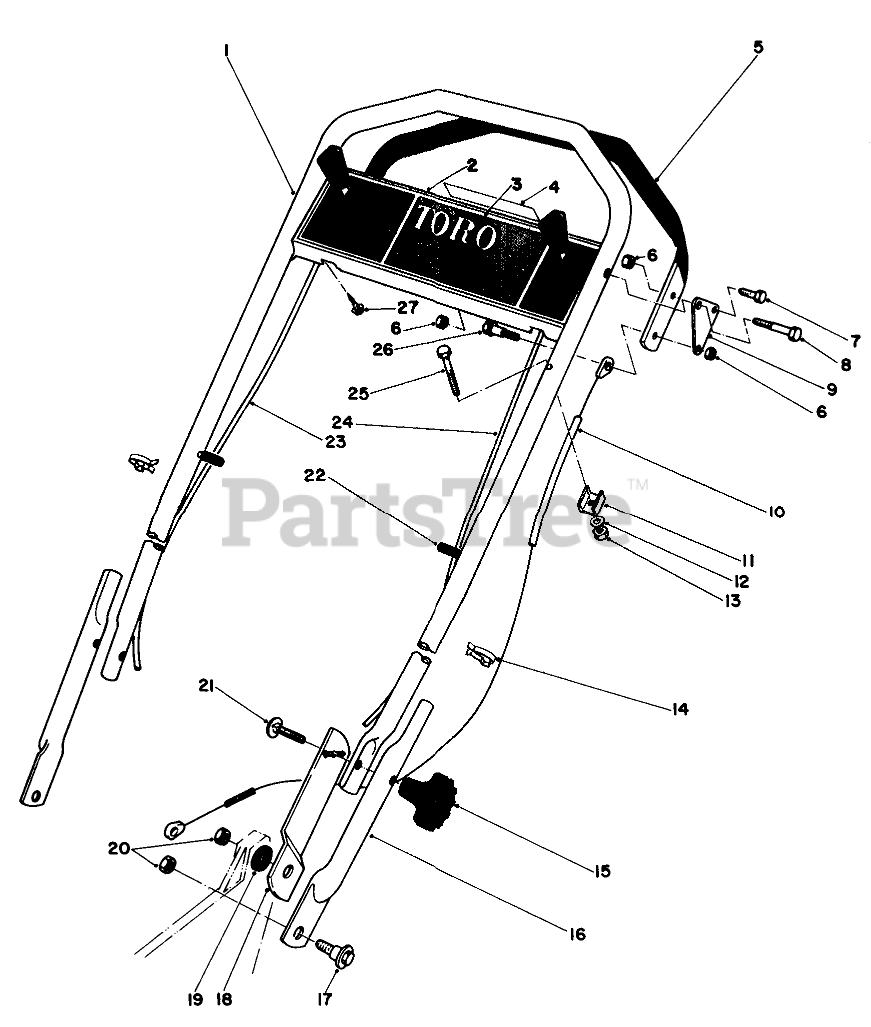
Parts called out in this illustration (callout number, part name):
1	Upper Handle
2	Control Plate (Incl. Ref. #3)
3	Decal-Control Panel
4	Decal-Select-a-Pace
5	DEMAND HANDLE ASM
6	NUT-LOCK, CONE
7	SCREW-HH
8	BOLT-SHOULDER
9	Bracket Demand
10	DEMAND HAND CABLE
11	CLAMP-CABLE
12	WASHER-FLAT
13	NUT-LOCK, NI
14	BOWDEN CLIP
16	LOWER HANDLE
17	SCREW-SHOULDER
18	Handle Latch L.H.
19	HANDLE LATCH SPACER
20	Nut
21	SCREW-CARR
22	CAP-VINYL
23	GROUND SPEED CONTROL
24	Throttle Control
25	SCREW-HH
26	SHOULDER BOLT
27	SCREW-HWHTF
